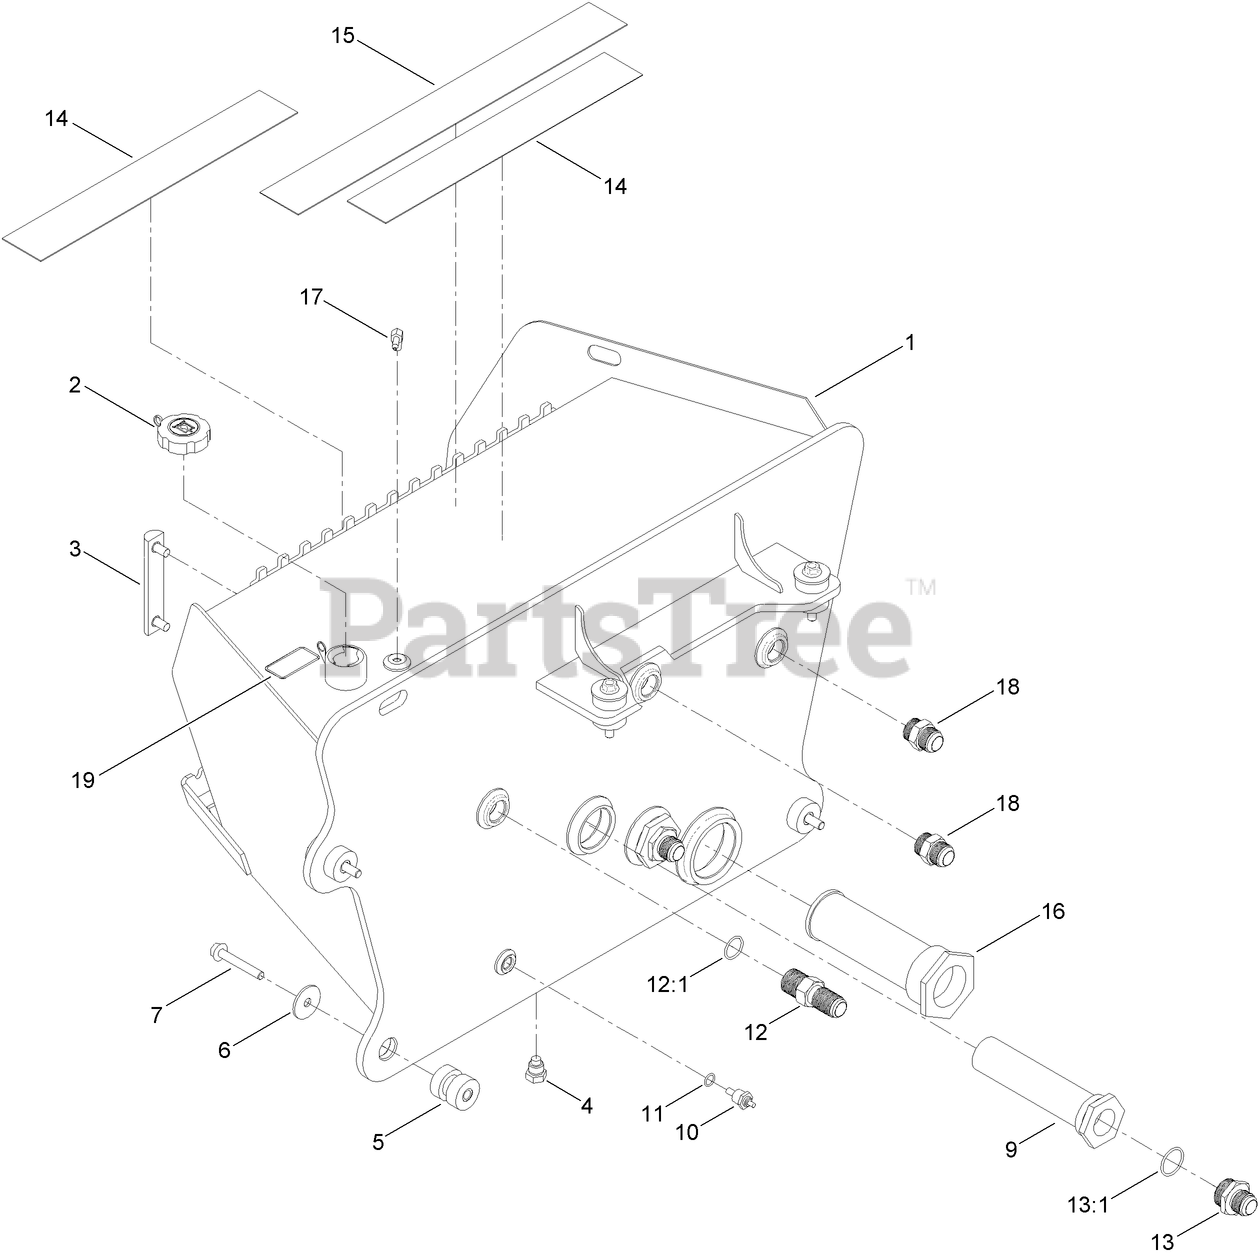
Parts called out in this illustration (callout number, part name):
1	TANK-HYDRAULIC
2	CAP-HYD FLUID (W/ LOCK)
3	GAUGE-SIGHT
4	PLUG-HEX, MAGNETIC
5	ISOLATOR-MOUNTING, UNIVERSAL
6	WASHER-FLAT
7	SCREW-HHF
9	STRAINER-MOUNTED, TANK
10	SENSOR-SENDER, OIL/WATER TEMP
12:1	O-RING
13	ADAPTER-STRAIGHT
13:1	O-RING
14	TAPE-ANTI SKID, LOWER STEP
15	STRIP-ANTI SKID
16	STRAINER-SUCTION
17	STEM-90 (BARB HOSE)
18	FITTING-STRAIGHT
19	DECAL-HYD FLUID
